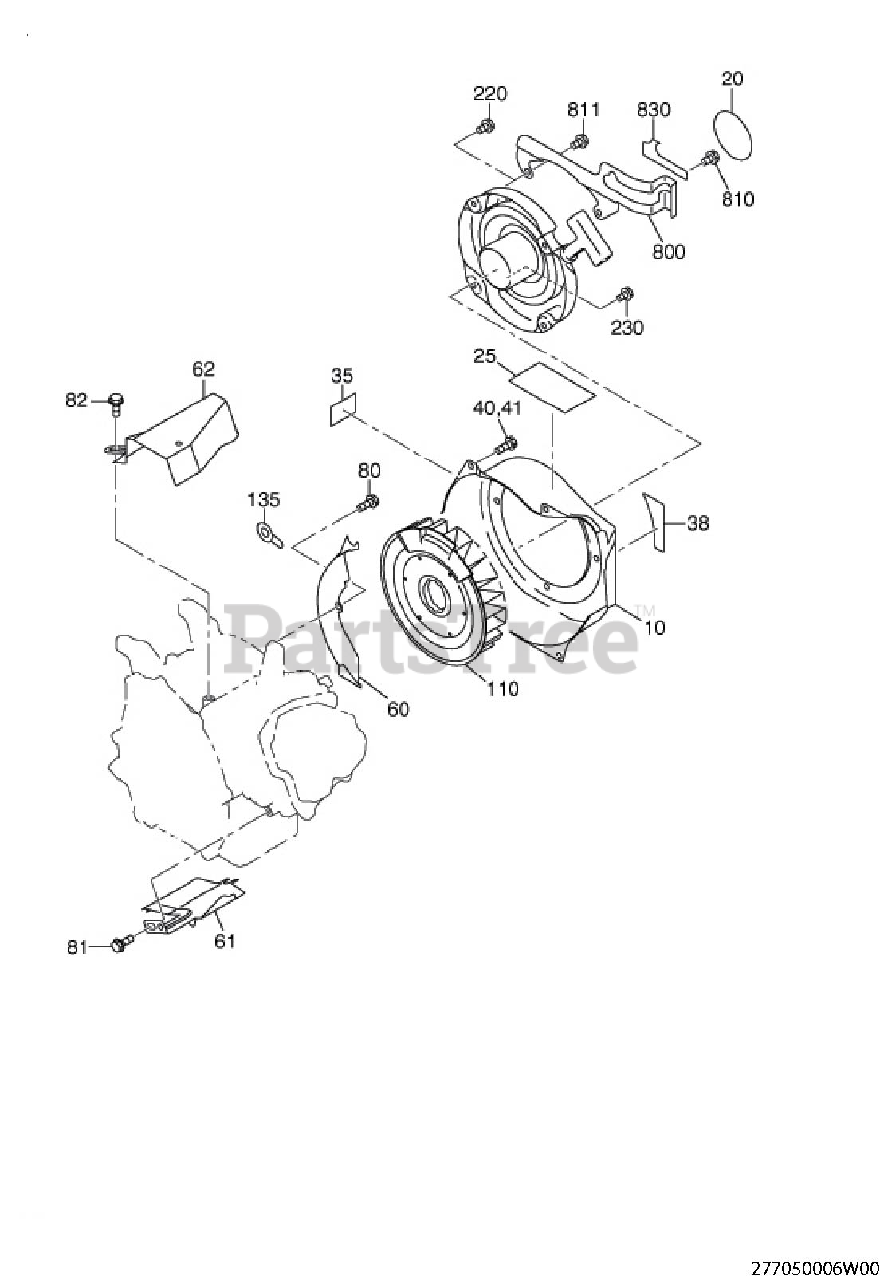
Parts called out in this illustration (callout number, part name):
10	BLOWER HOUSING CP
20	LABEL, TRADEMARK
60	BAFFLE 1 CP,CASE
61	BAFFLE 2, HEAD
110	COOLING BLOWER
810	SCREW AND WASHER AY
811	SCREW AND WASHER AY
